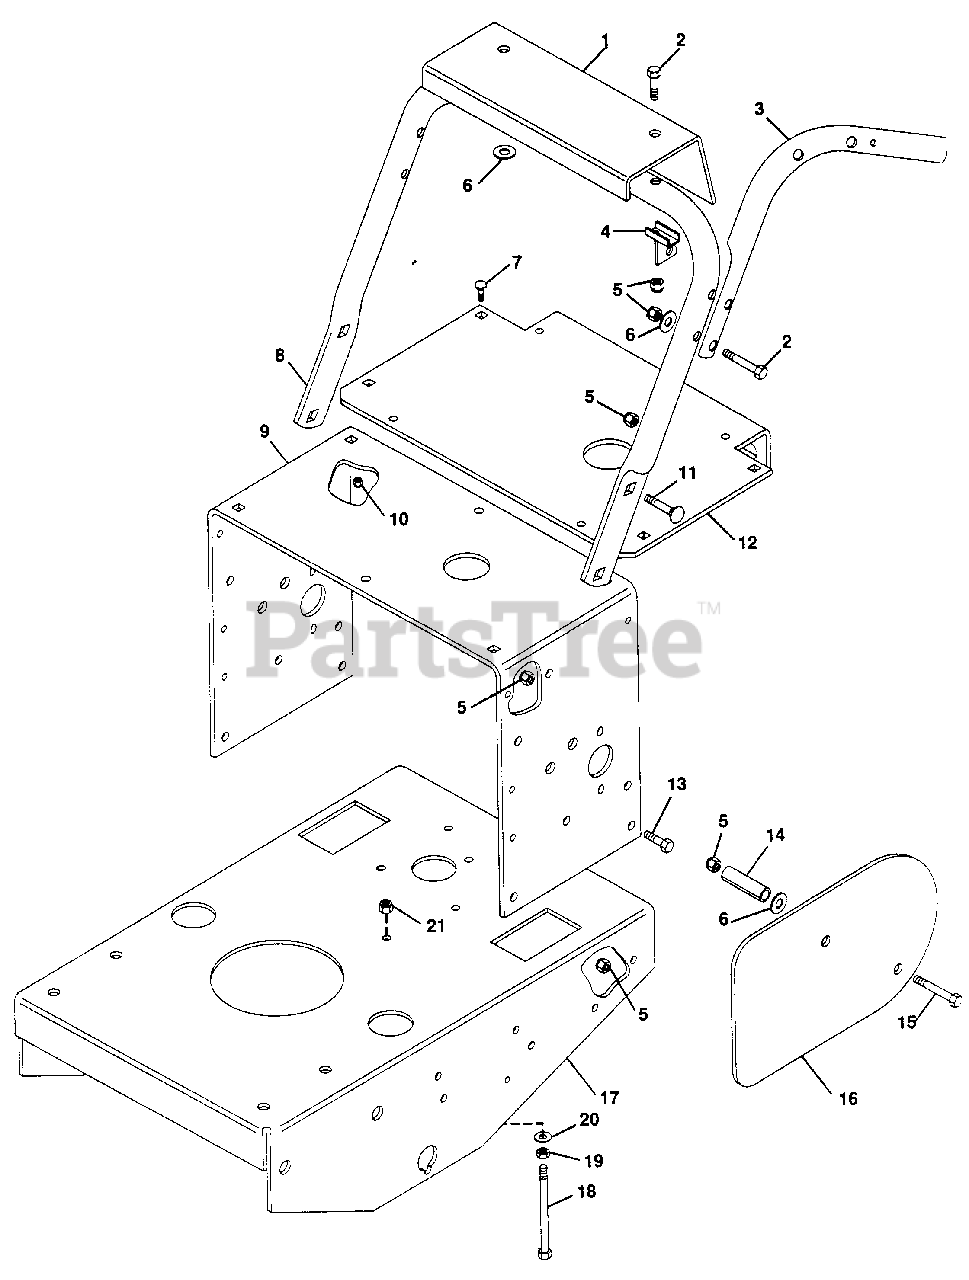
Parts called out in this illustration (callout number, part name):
1	PANEL, SILK SCREEN
2	BOLT, HEX 3/8-16X2.00
3	HANDLEBAR, L.H.
3	HANDLEBAR, R.H.
4	WELDMENT, PTO LEVER MOUNTING
5	NUT, LOCK 3/8-16
6	WASHER, FLAT .406X.812X.065
7	BOLT, 1/4-20X.625 RD HD SQ NK
8	TUBE, HANDLEBAR MOUNTING
9	SUPPORT, HANDLEBAR
10	NUT, LOCK 1/4-20
11	BOLT, 3/8-16X1.00 RD HD SQ NK
12	PLATE, SILK SCREEN
13	BOLT, HEX 3/8-16X1.00
14	BUSHING, ST .401X.553X2.25 STL.
15	BOLT, HEX 3/8-16X2.25
16	GUARD, SILK SCREENED L.H.
16	GUARD, SILK SCREENED R.H.
17	FRAME, PRO 32
18	BOLT, HEX 3/8-16X4.00
19	NUT, HEX 3/8-16
20	WASHER, FLAT .406X.812X.065
21	NUT, LOCK 3/8-16
